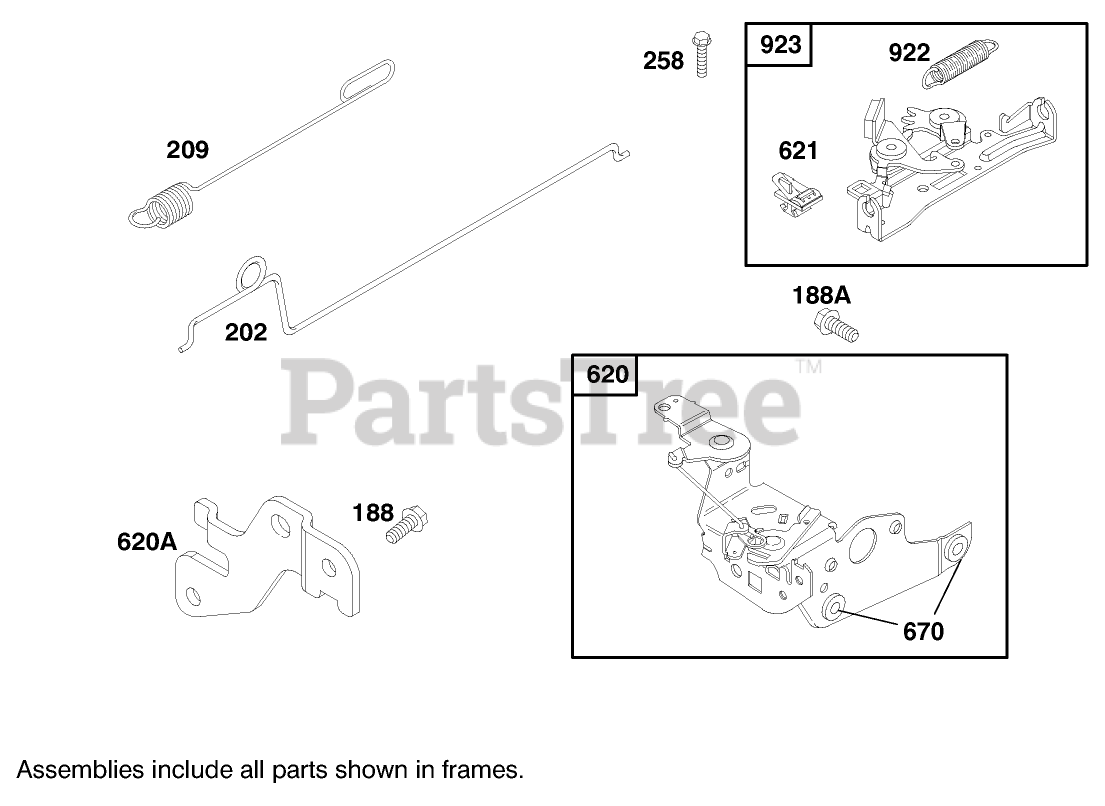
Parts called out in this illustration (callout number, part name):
188	Screw-Hex.
188A	Screw-Hex.
202	Link-Govemor
209	Spring-Governor
258	Screw-Sem
620	Bracket-Carburetor
670	Spacer
922	Brake Spring
923	Brake
